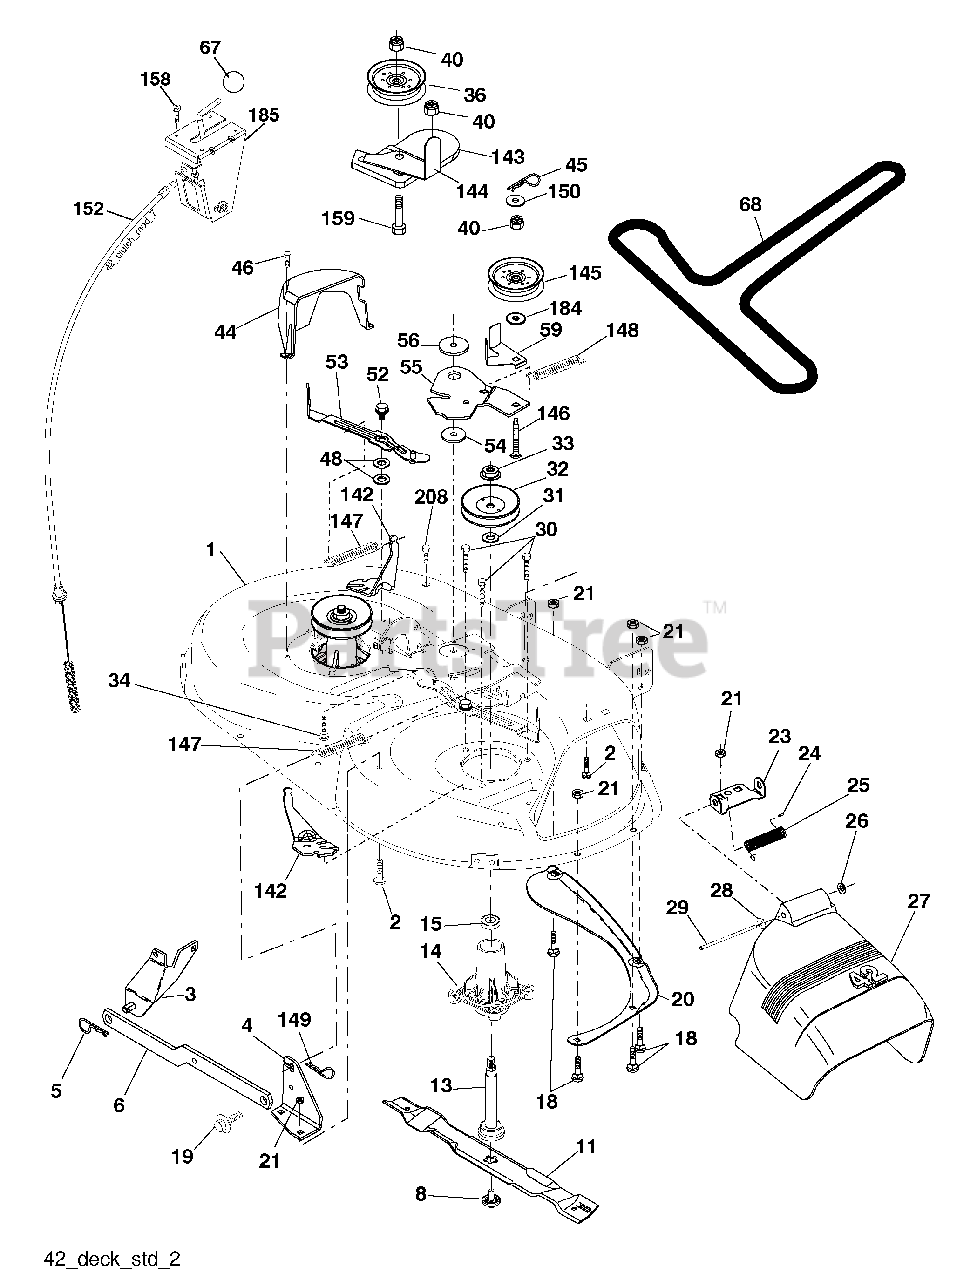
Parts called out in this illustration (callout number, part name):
1	Mower Deck Assembly, 42"
2	Bolt
3	Bracket Asm Fr. Sway Bar 3/42
4	Bracket Asm Deck 42" Sway Bar
5	Retainer Spring
6	Bar Sway Deck
8	Bolt/Washer Asm. 7/16-20 unf (The following Blades are available)
11	Blade Mower 42" Hi-Lift (for bagging and discharging)
11	Blade, Mulching 42" Std (for mulching mowers only)
11	Blade Mulching 42" Premium (For better wear when mulching)
11	Blade 42 3N1
11	Blade 42 3N1 Premium
13	Shaft As m. Mandrel
14	Housing Mandrel
15	Bearing, Ball, Mandrel
18	Bolt, Carriage 5/16-18 x 5/8
19	Bolt, Shoulder
20	Baffle, Vortex
21	Nut
23	Bracket, Deflector Mower 42"
24	Cap, Sleeve 80 x 112 Blk Mower
25	Spring, Torsion, Deflector 2 52
26	Nut, Push Phos & Oil
27	Shield, Deflector 42" Blk
28	Washer 11/32 x 5/8 x 16 Ga.
29	Rod, Hinge 42" 6 75 w/G
30	Screw Thdrol
31	Washer, Spacer Mower Vented
32	Pulley, Mandrel
33	Nut, Toplock
34	Bolt Carr SH 3/8-16 x 1-1/2 Gr.5
36	Pulley, Idler, Flat
40	Nut Lock 3/8-16
44	Guard, Mandrel, LH
45	Retainer
46	Screw, Thdrol 1/4-20 x 5/8 T
48	Washer, Hardened
52	Bolt, Shoulder 5/16-18 unc
53	Arm Assembly, Pad, Brake
54	Washer, Hardened
55	Arm, Idler
56	Spacer, Retainer
59	Guard TUV Idler
67	Knob Round
68	V-Belt, 42" Mower
142	Anchor Spring Brake Mower
143	Bracket Arm Idler 42"
144	Keeper Belt 42" Clutch Cable
145	Pulley Idler Flat
146	Bolt Carriage Idler
147	Spring Extension
148	Spring Return Idler
149	Retainer Spring Yellow
150	Washer 9/32 x 3/4 x 10 Ga.
152	Clutch Cable 42"
158	Screw Hex Thd Cut 1/4-20 x 1/2
159	Bolt Rdhd Sqn 3/8-16 unc x 1-3/4
184	Washer 13/32 x 7/8 x 10 Ga.
185	Head Asm Cable Clutch
208	Screw 3/8-16 x 1/2
208	Mandrel Assembly
208	Replacement Mower, Complete
